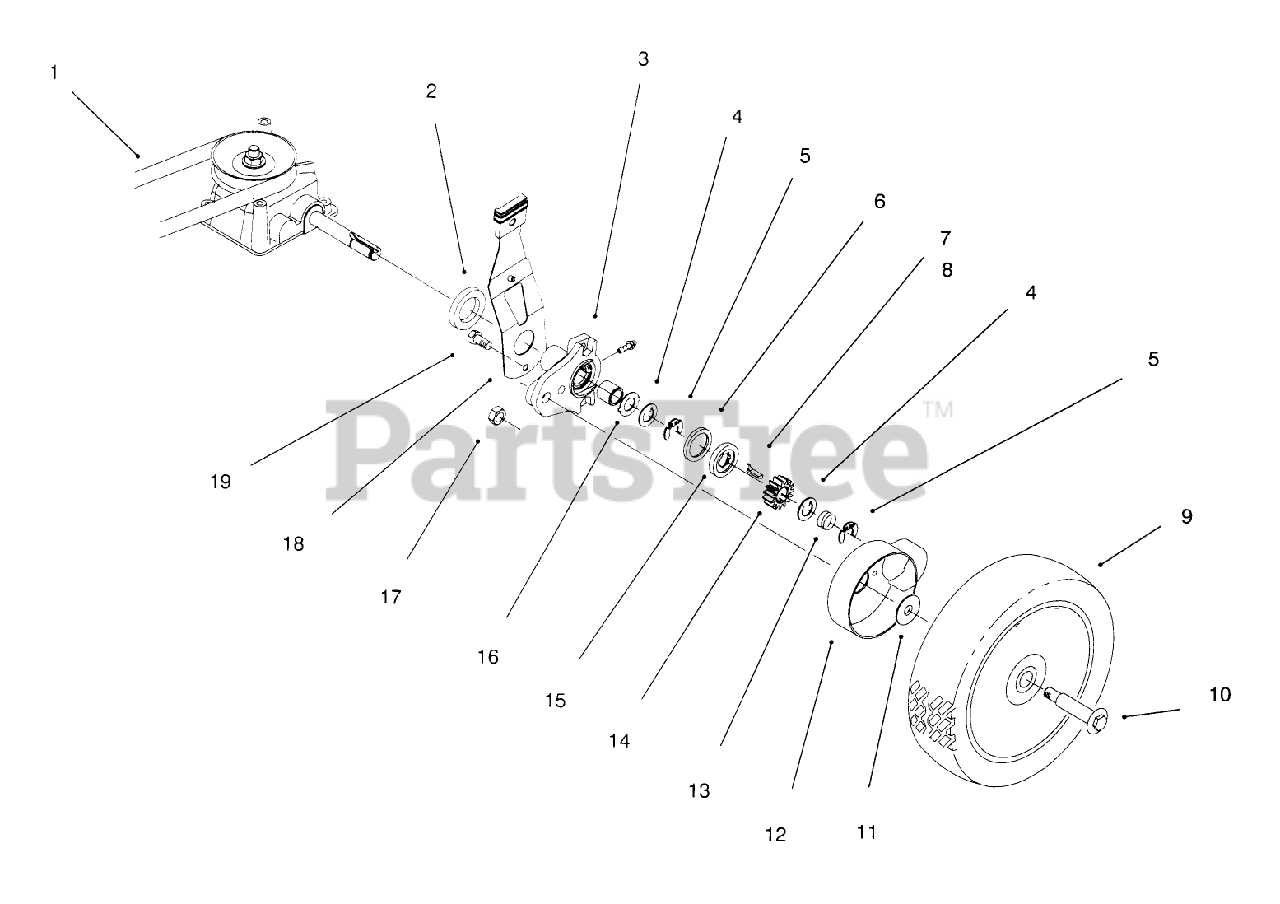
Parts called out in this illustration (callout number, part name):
1	V-BELT
2	SPACER-SHAFT, AXLE
3	REAR HEIGHT ADJUSTMENT ARM ASM
4	WASHER-THRUST, KEYED
5	RING-RETAINING,CLIP
6	RING-FRICTION
7	KEY-ROCKING, RH
8	KEY-ROCKING, LH
9	WHEEL ASM
10	BOLT-SHOULDER
11	WASHER-STEPPED
12	COVER-WHEEL
13	SPRING-COMPRESSION
14	GEAR-PINION
15	WASHER-CLUTCH
16	WASHER-ARM, PIVOT
17	NUT-JAM, LOCKING
18	REAR SPRING ARM ASM
19	SCREW-HWH
